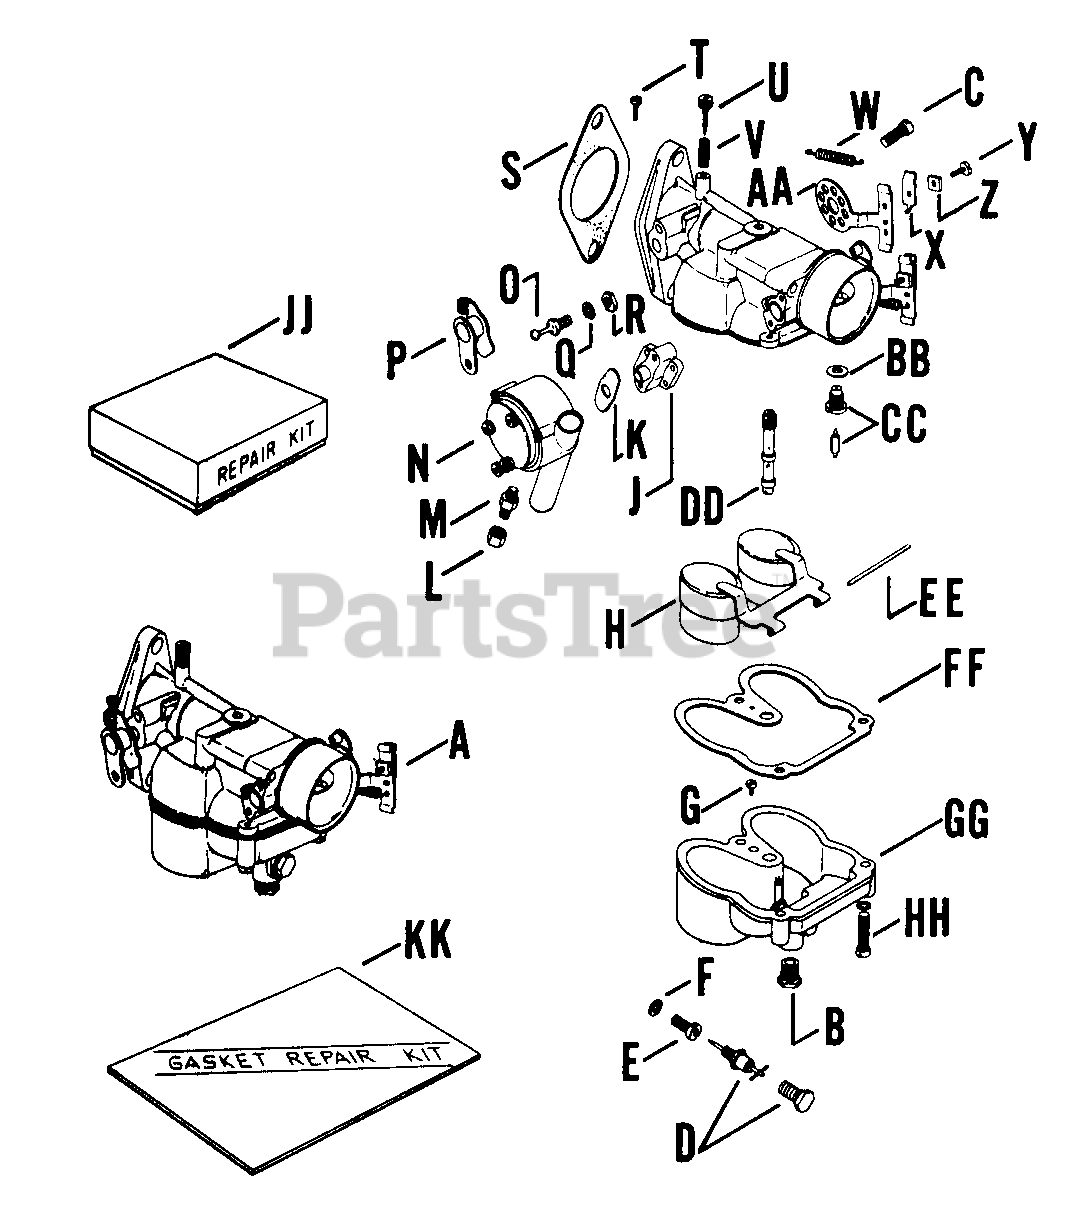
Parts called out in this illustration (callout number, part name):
A	CARBURETOR ASSY - DISCONTINUED
B	PLUG, PIPE DISCONTINUED
D	PLUG - DISCONTINUED
E	Jet, main
F	WASHER - DISCONTINUED
O	JOINT - DISCONTINUED
P	Lever and stop, throttle
Q	WASHER, SPRING LOCK #10
S	GASKET - DISCONTINUED
W	Spring, choke lever
EE	Axle, float
FF	GASKET - DISCONTINUED
GG	Bowl, fuel
JJ	KIT - DISCONTINUED
